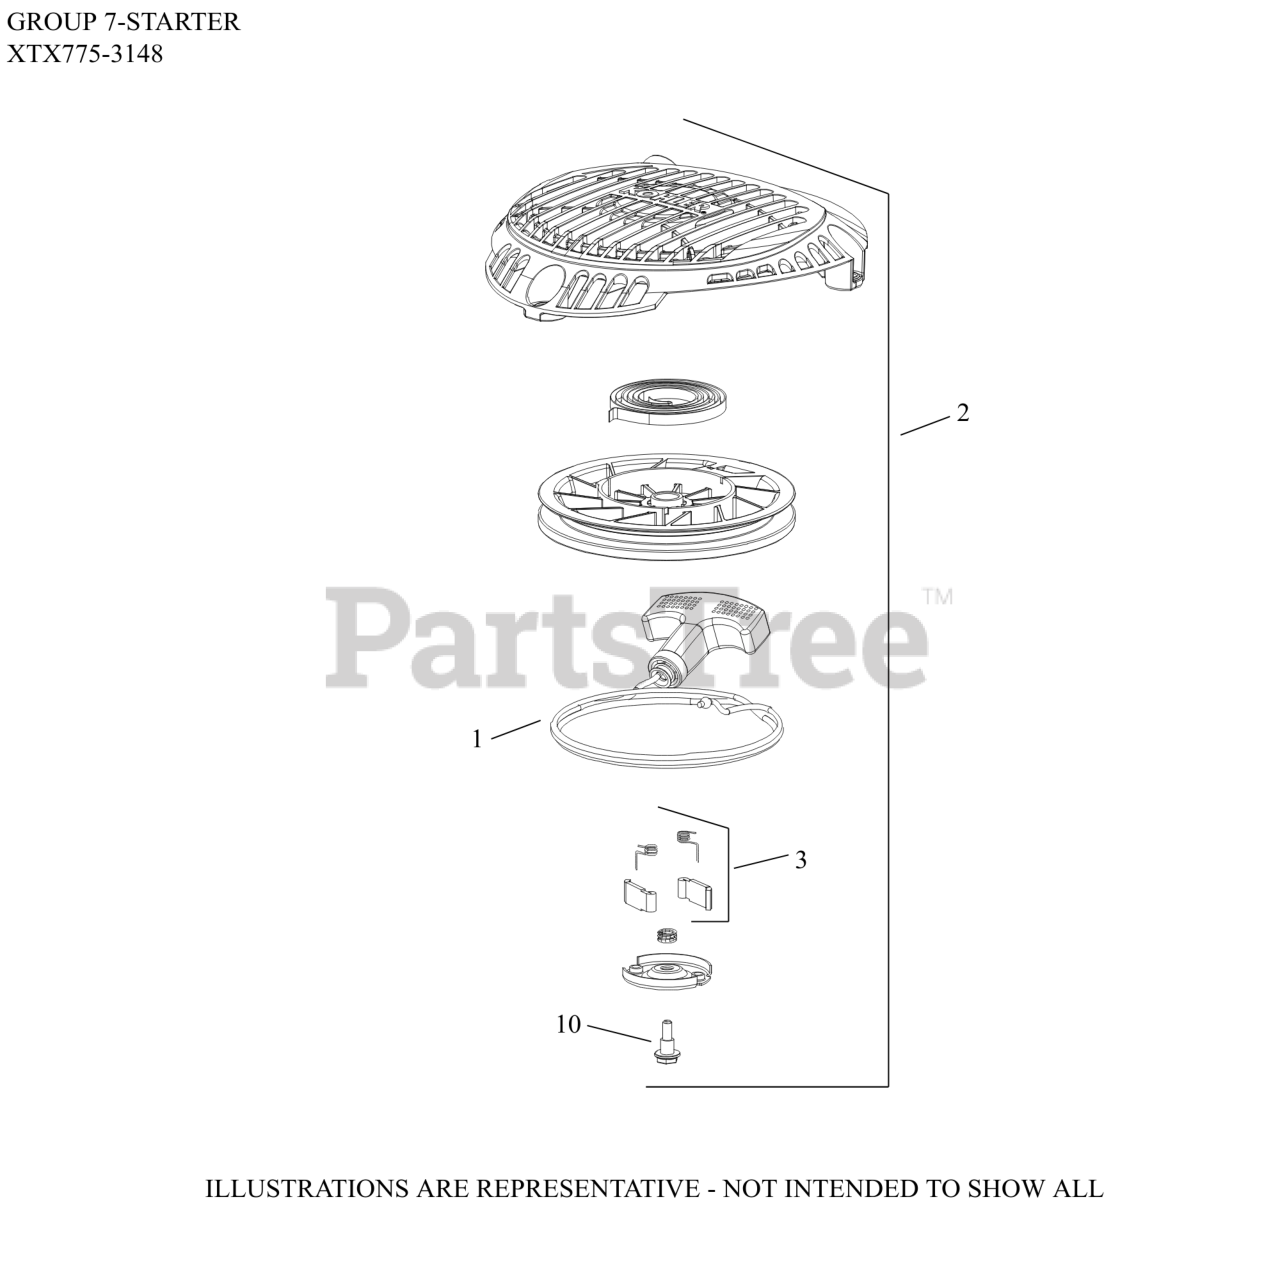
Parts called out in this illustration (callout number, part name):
1	KIT, STARTER ROPE W/HANDLE
2	STARTER ASSY-RETRACT-USE 14 165 21-S
3	KIT, PAWL REPAIR
10	SCREW, SHOULDER (M5)
